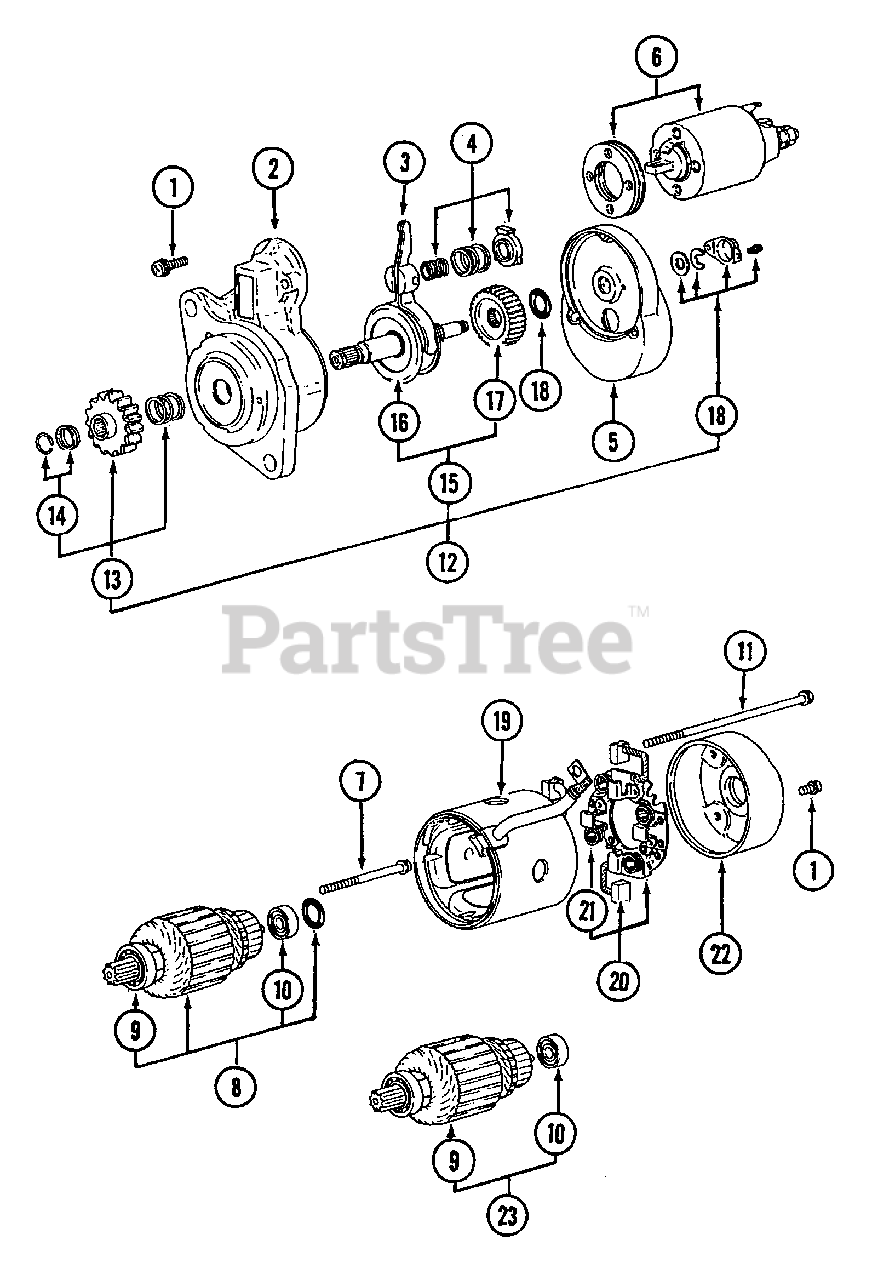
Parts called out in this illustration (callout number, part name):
2	Front Bracket Ass'y.
3	Lever Ass'y.
5	Center Bracket Ass'y.
6	Switch Ass'y.
8	Armature Set
12	Clutch Set Shaft Ass'y.
14	Stopper Set
16	Pinion Shaft Ass'y.
19	Yoke Ass'y.
20	Brush Holder Ass'y.
21	Spring, Brush
22	Bracket, Rear
23	Service Kit, Starter Bearing
